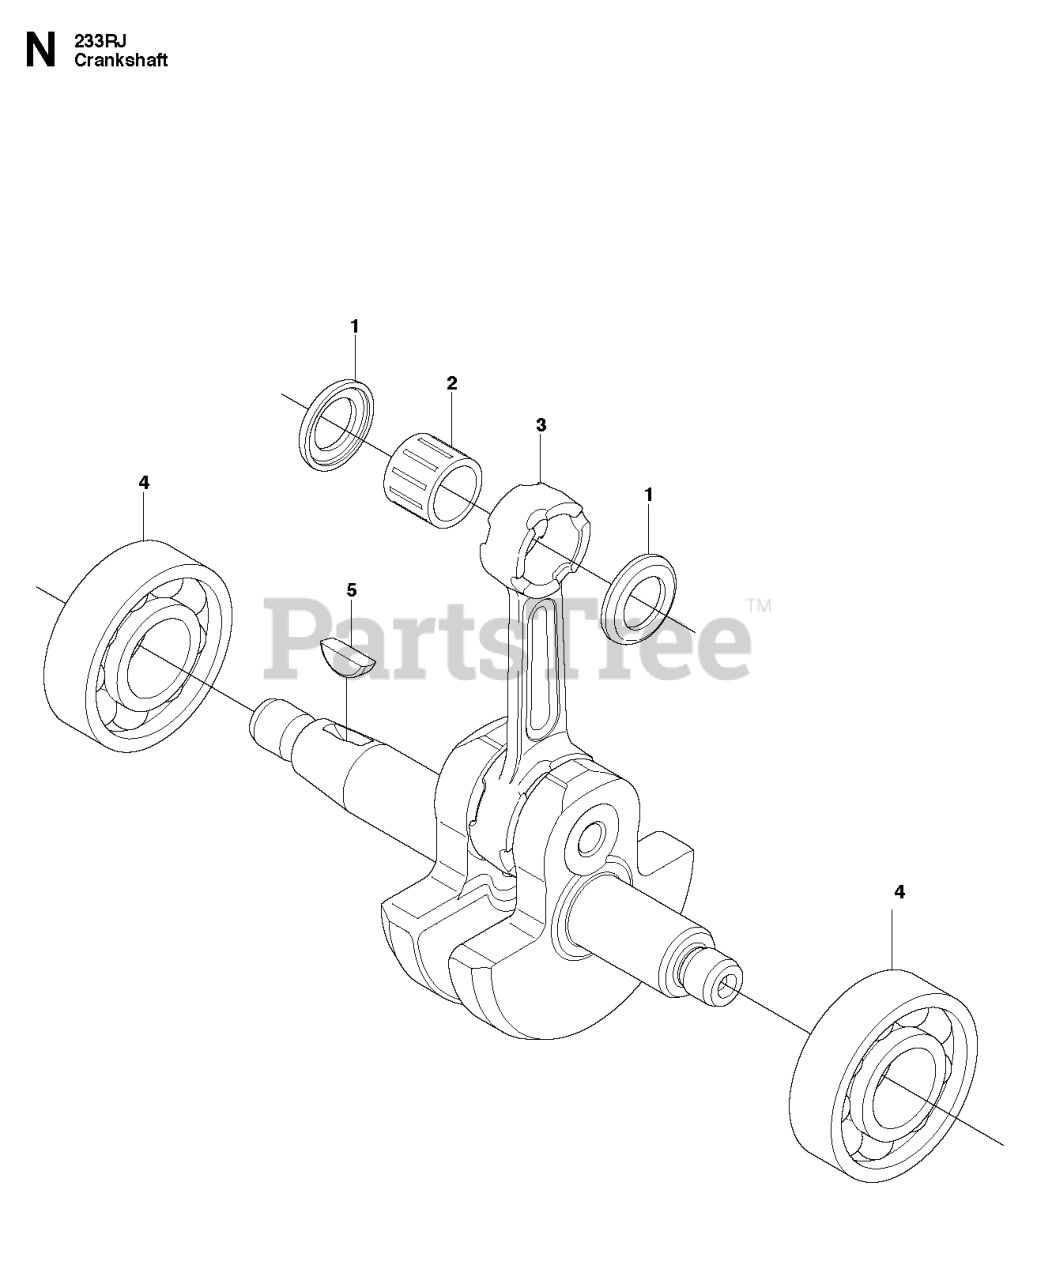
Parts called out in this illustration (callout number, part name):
1	WASHER (RPLS 331041341)
2	BEARING
3	CRANKSHAFT-C
4	BEARING CRANKSHAFT
